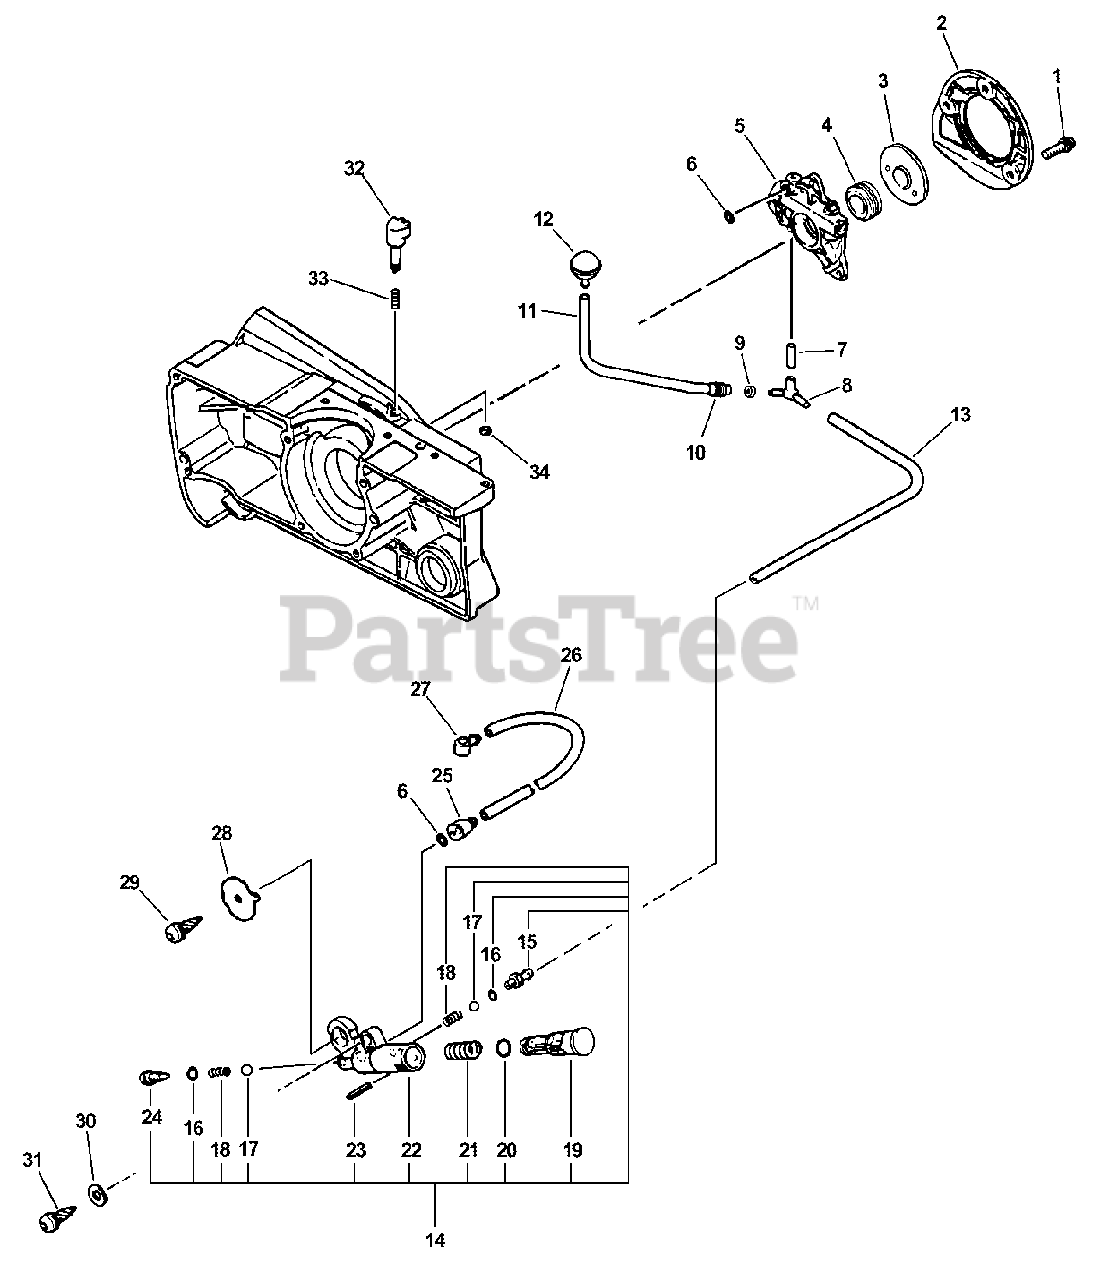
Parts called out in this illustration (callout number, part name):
1	SCREW - 4X12
2	COVER, OIL PUMP
3	WASHER - 12
4	GEAR - WORM
5	AUTO-OILER ASSY
6	O-RING - 3
7	PIPE - 3X6X20 -- BLACK
8	CONNECTOR, PIPE
9	CLIP - 6.5
11	PIPE - OIL
12	FILTER, OIL
13	PIPE - 3X6X200 -- BLACK
14	OIL PUMP ASSY
17	VALVE, BALL
19	PISTON, OIL PUMP
20	O-RING - 7
22	BODY, OIL PUMP
23	PIN - SPRING -- 2X16
24	ADAPTER, OIL PUMP
25	CONNECTOR, PIPE
26	PIPE, OIL - 3X6X125
27	CONNECTOR, PIPE
28	BRACKET, OIL PUMP
29	SCREW - 4X10
30	WASHER - 5
31	SCREW - 5X20
32	DIAL, AUTO-OILER
34	RING, RETAINING - 3
